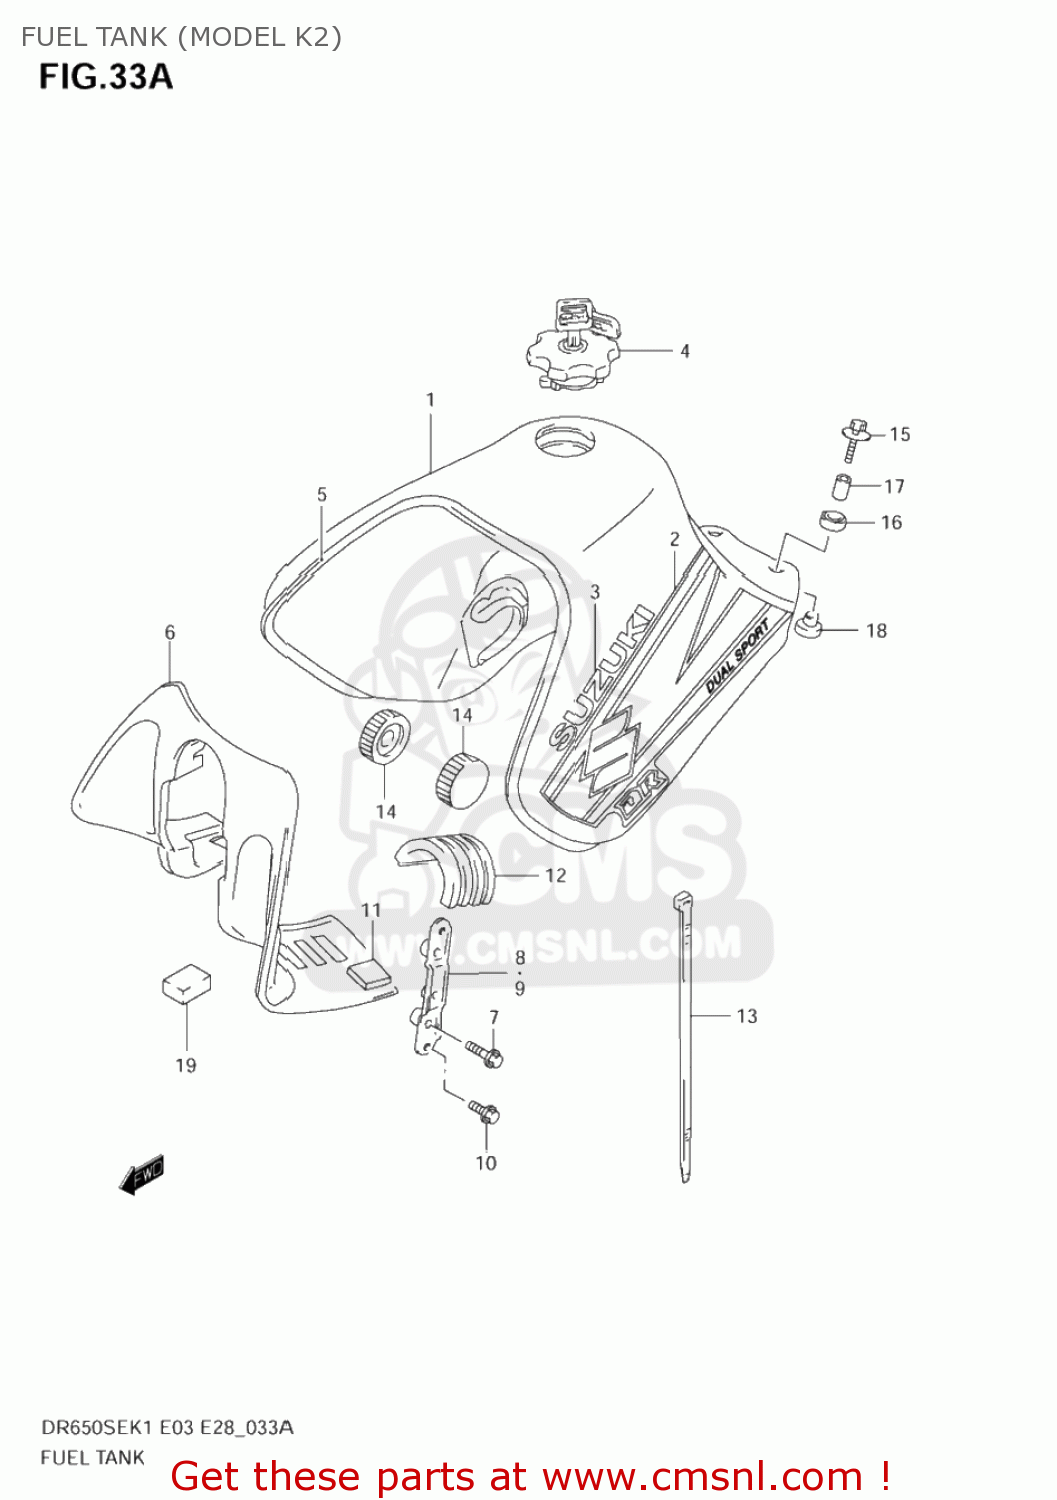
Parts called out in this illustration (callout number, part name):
1	TANK ASSY,FUEL(BLUE)
2	TAPE SET,FUEL TANK
3	EMBLEM,FUEL TANK
4	CAP SET,FUEL TANK
5	MOLDING,FUEL TANK
6	COVER,FUEL TANK FR
7	BOLT 6X14
8	BRACKET,FUEL TANK COVER,R
9	BRACKET,FUEL TANK COVER,L
10	BOLT
11	CUSHION,HEADLAMP COVER
12	CUSHION,FUEL TANK UPR
13	CLAMP(L:250)
14	CUSHION,FUEL TANK FR
15	BOLT(6X30)
16	CUSHION
17	SPACER(6.5X9X18)
18	CUSHION
19	CUSHION
